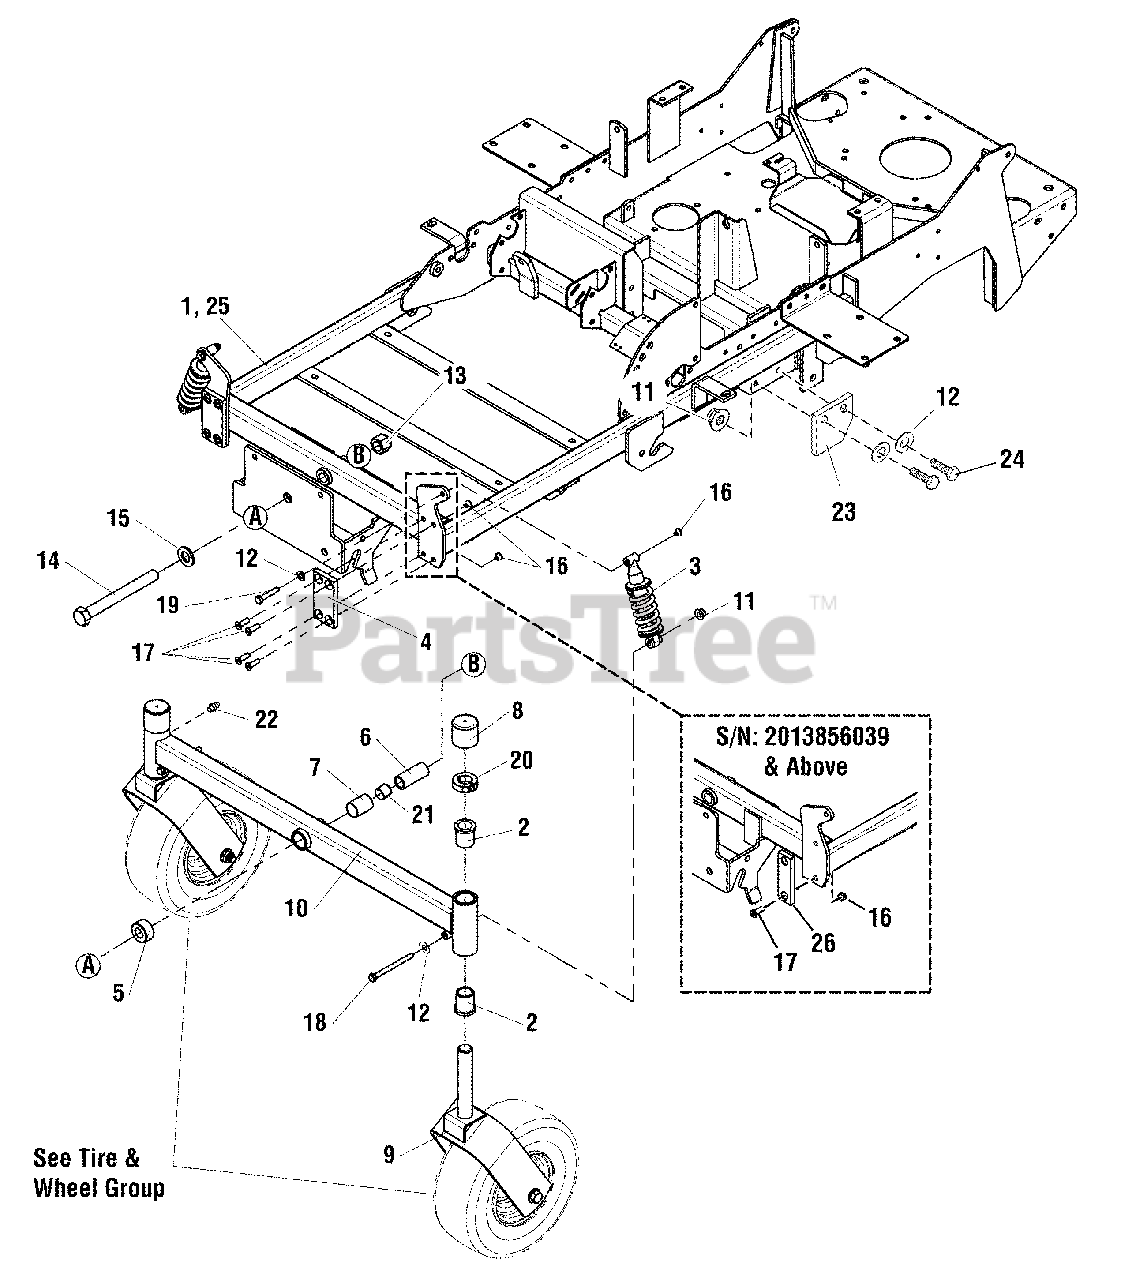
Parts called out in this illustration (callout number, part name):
1	WELD, MAIN FRAME, SMI
2	BUSHING, FLANGE
3	SHOCK, SPRING ASSEMBLY
4	DECK FRICTION REDUCER PLATE
5	SPACER, .76X 1.50 X .79
6	SPACER, .75 X 1.00 X 2.38
7	PIVOT BEARING, 1.00" X 1.125" OD X 1.50"
8	CAP, VINYL 1.687 X 1-1/2
9	WELD,CASTER YOKE
10	WELD, PIVOTING FRONT END - ORG
11	NUT, 5/16-18 HEX NYLOCK FLANGE
12	WASHER, 5/16" SAE
13	NUT, 3/4-16 HEX NYLON LOCK
14	BOLT, GD5, YZ, 3/4-16 X 7"
15	WASHER, 3/4" SAE
16	NUT, 5/16-18 HEX
17	SCREW, 5/16-18 X 1", PHILLIPS HD, BZ
18	BOLT, 5/16-18 X 3-3/4 GD5
19	BOLT, 5/16-18 X 1-3/4" GD5 YZ
20	COLLAR, 1" SPLIT
21	PIVOT BEARING, 1.00" X 1.125" OD X .50"
22	GREASE FITTING, 1/4-28 STRAIGHT
23	PLATE, DECK STOP
24	BOLT, 5/16-18 X 3/4" GD5
25	WELD, MAIN FRAME, SMI
26	PAD, FRICTION, .375 X 1.25 X 4.00
